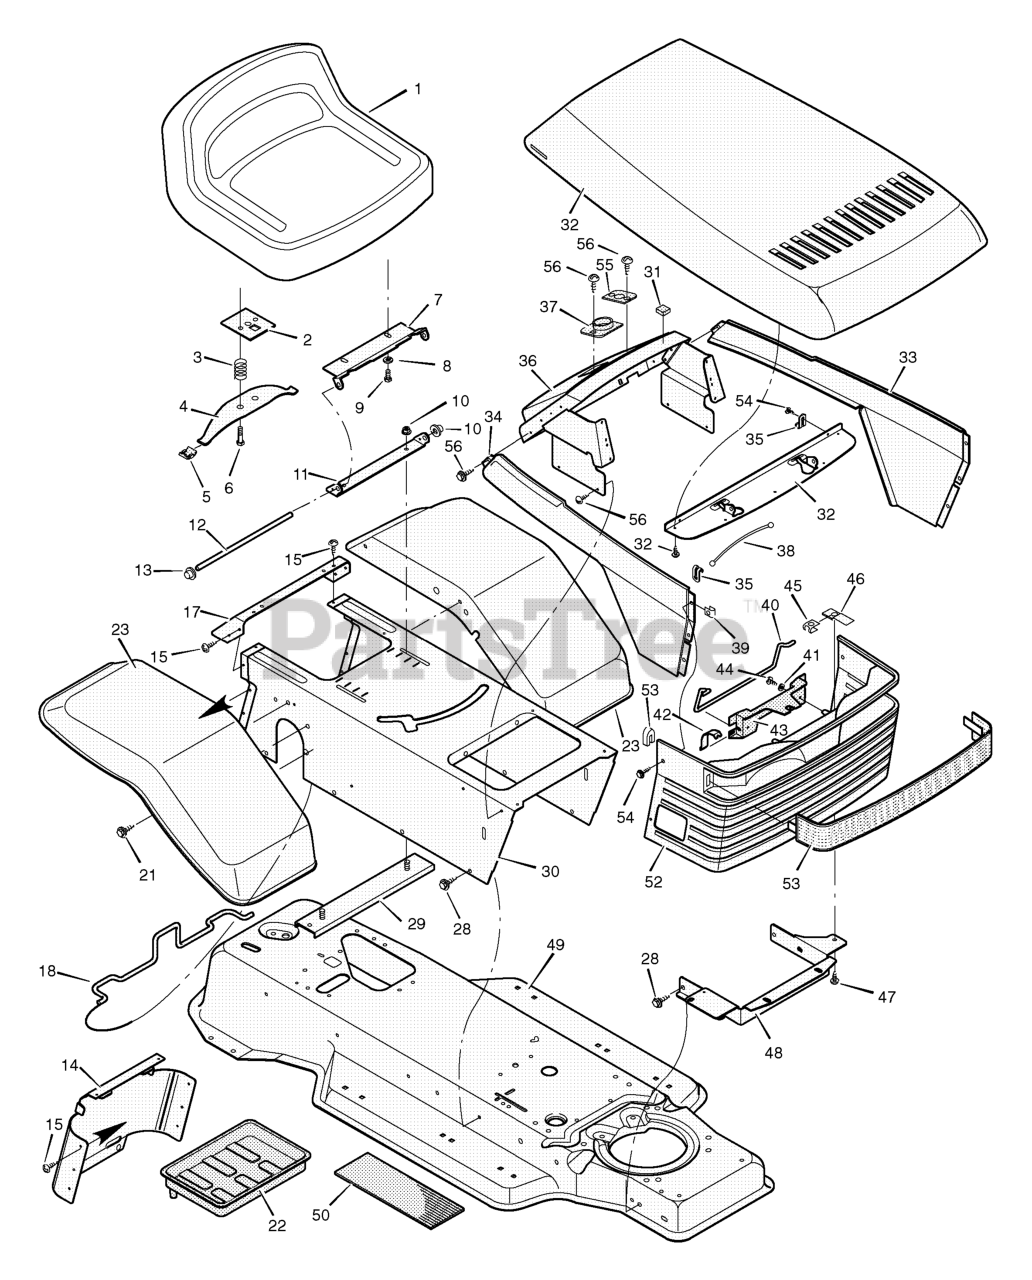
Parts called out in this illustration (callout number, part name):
2	Plate Assembly, Switch
3	Spring, Compression
4	Spring, Seat
5	Glide, Spring
6	Bolt, Shoulder
7	Support, Seat
8	Lockwasher
9	Bolt, Hex
10	Locknut, Flange
11	Bracket, Pivot
12	Rod, Pivot
13	Cap, Push On
14	Cap, Console
15	Screw
17	Fender, Apron
18	Clamp, Battery
22	Tray, Battery
29	Channel Assembly
30	Console Assembly
31	Trim, Edge
32	Hood Assembly
33	Panel, Left
34	Panel, Right
35	Clip, Cable
36	Dash Assembly
37	Bearing, Steering
39	U- Fastener
40	Rod, Hinge
41	Washer
42	Spring, Hood
43	Bracket, Hood Mount
45	Nut, Speed
46	Shield, Heat
48	Support, Grille
49	Frame Assembly
53	Lens
55	Bearing
